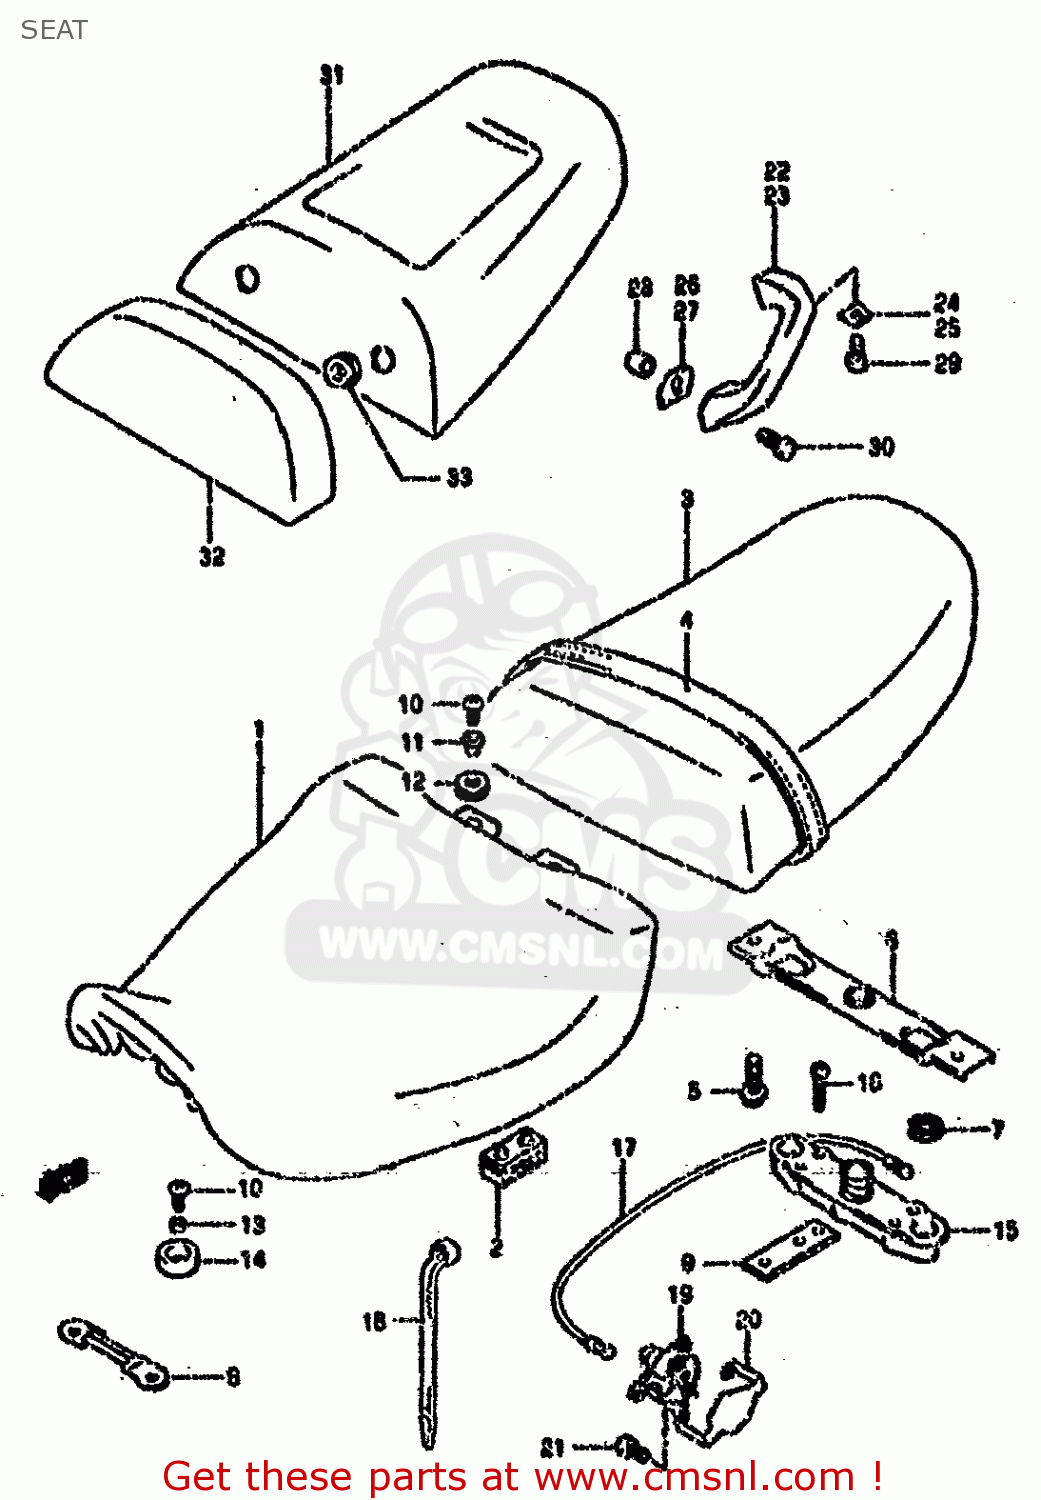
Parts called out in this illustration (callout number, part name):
1	SEAT ASSEMBLY
2	CUSHION,SEAT(40X20X15)
3	SEAT ASSEMBLY,PILLION
4	BAND COMP,SEAT
5	BOLT
6	STRIKER,SEAT LOCK
7	CUSHION
8	PLATE,SEAT FR HOOK
9	BRACKET COMP,SEAT SUPPORT
10	SCREW
11	WASHER
12	CUSHION
13	SPACER (6.8X10X4.7)
14	CUSHION,TAIL COVER UPR
15	LOCK ASSY,SEAT STRIKER
16	SCREW
17	CABLE,SEAT LOCK
18	CLAMP L:165
19	LOCK SET,SEAT
20	PLATE,SEAT LOCK GUARD
21	SCREW(6X12)
22	HANDLE,PILLION RIDER,R
23	HANDLE,PILLION RIDER,L
24	CUSH.,PILLION
25	CUSHION,PILLION HANDLE UPR,L
26	CUSHION,PILLION HANDLE LWR,R
27	CUSH,PILLIONL
28	BOLT
29	BOLT
30	SPACER(8.6X16X20)
31	BOX SET,SEAT TAIL
32	BACKREST COMP,SEAT
33	CUSHION
